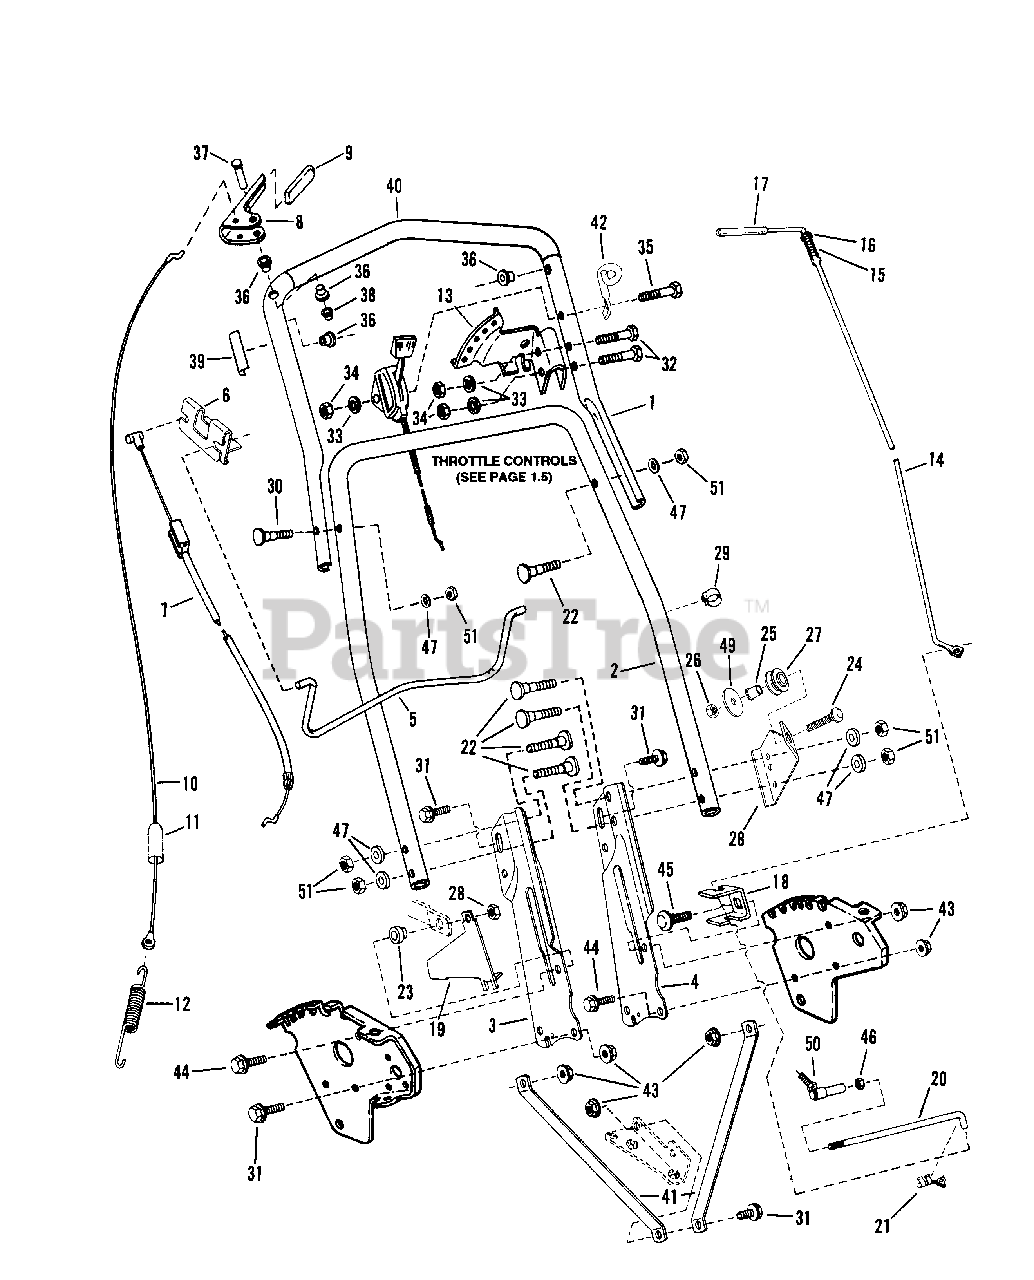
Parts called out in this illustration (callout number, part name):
1	HANDLE, Upper
2	HANDLE, Middle
3	HANDLE, Lower Right Hand
4	HANDLE, Lower Left Hand
5	CONTROL, Blade
6	CLIP, Blade Control
7	CABLE, Blade Control
8	HANDLE, Wheel Drive
9	GRIP, Wheel Drive Handle
10	CABLE, Clutch Pull (Z-Bend)
11	COVER, Vinyl
12	SPRING, Clutch
13	SECTOR, Speed
14	LEVER, Speed Control
15	SPRING, Speed Control
16	WASHER, 3/8" Flat
17	GRIP, Speed Control Handle
18	ANCHOR, Speed Control
19	GUIDE, Lower V-Belt
20	ROD, Transfer
21	CLIP, Transfer Rod
22	BOLT, 5/16-18 x 1-1/2" Curved Head
23	BUSHING, Differential
24	BOLT, 3/8-16 x 1-1/2" Carriage
25	BUSHING Flange
26	NUT, 3/8-16 Hex Center Lock
27	PULLEY, Nylon
28	BRACKET, Rope Pulley
29	CLIP, Wiring Harness
30	SCREW, 1/4-20 x 1-7/8" Curved Head
31	BOLT, 5/16-18 x 3/4" Flange Lock
32	SCREW, 1/4-28 x 1-3/8" Hex Cap
33	WASHER, 1/4 Internal Tooth Lock
34	NUT, 1/4-20 Hex
35	SCREW, 1/4-28 x 1-3/4" Hex Cap
36	BUSHING
37	PIN, Clutch Handle
38	NUT, Push (for handle pin)
39	DECAL, Blade Control
40	GRIP, Foam
41	STRAP, Handle
42	BRACKET, Pull Rope
43	NUT, 5/16-18 Hex Flange Lock
44	BOLT, 5/16-18 x 1" Hex Flange Lock
45	BOLT, 5/16-18 x 1" Carriage
46	NUT, 1/4-28 Hex
47	WASHER, 5/16 Internal Tooth Lock
49	WASHER, 3/8 x 2" Flat
50	JOINT, Ball
51	NUT, 5/16-18 Hex
